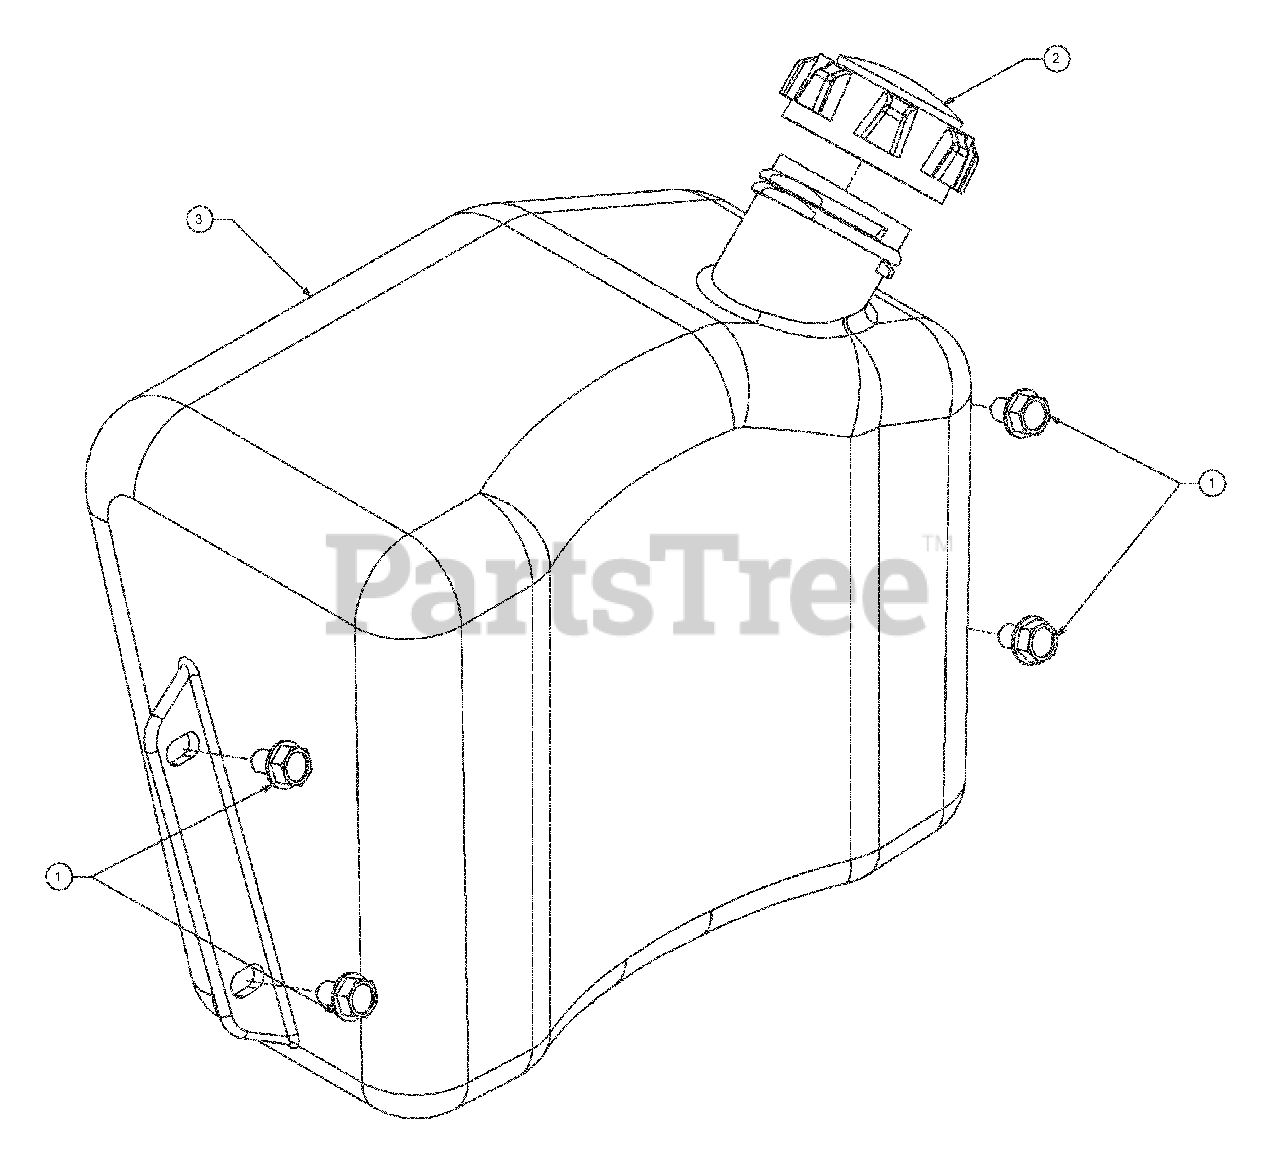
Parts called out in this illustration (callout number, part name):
1	SCR:TT:5/16-18:0.625:HXINDWSH
2	CAP:FUEL
3	TANK:FUEL:2 GAL
